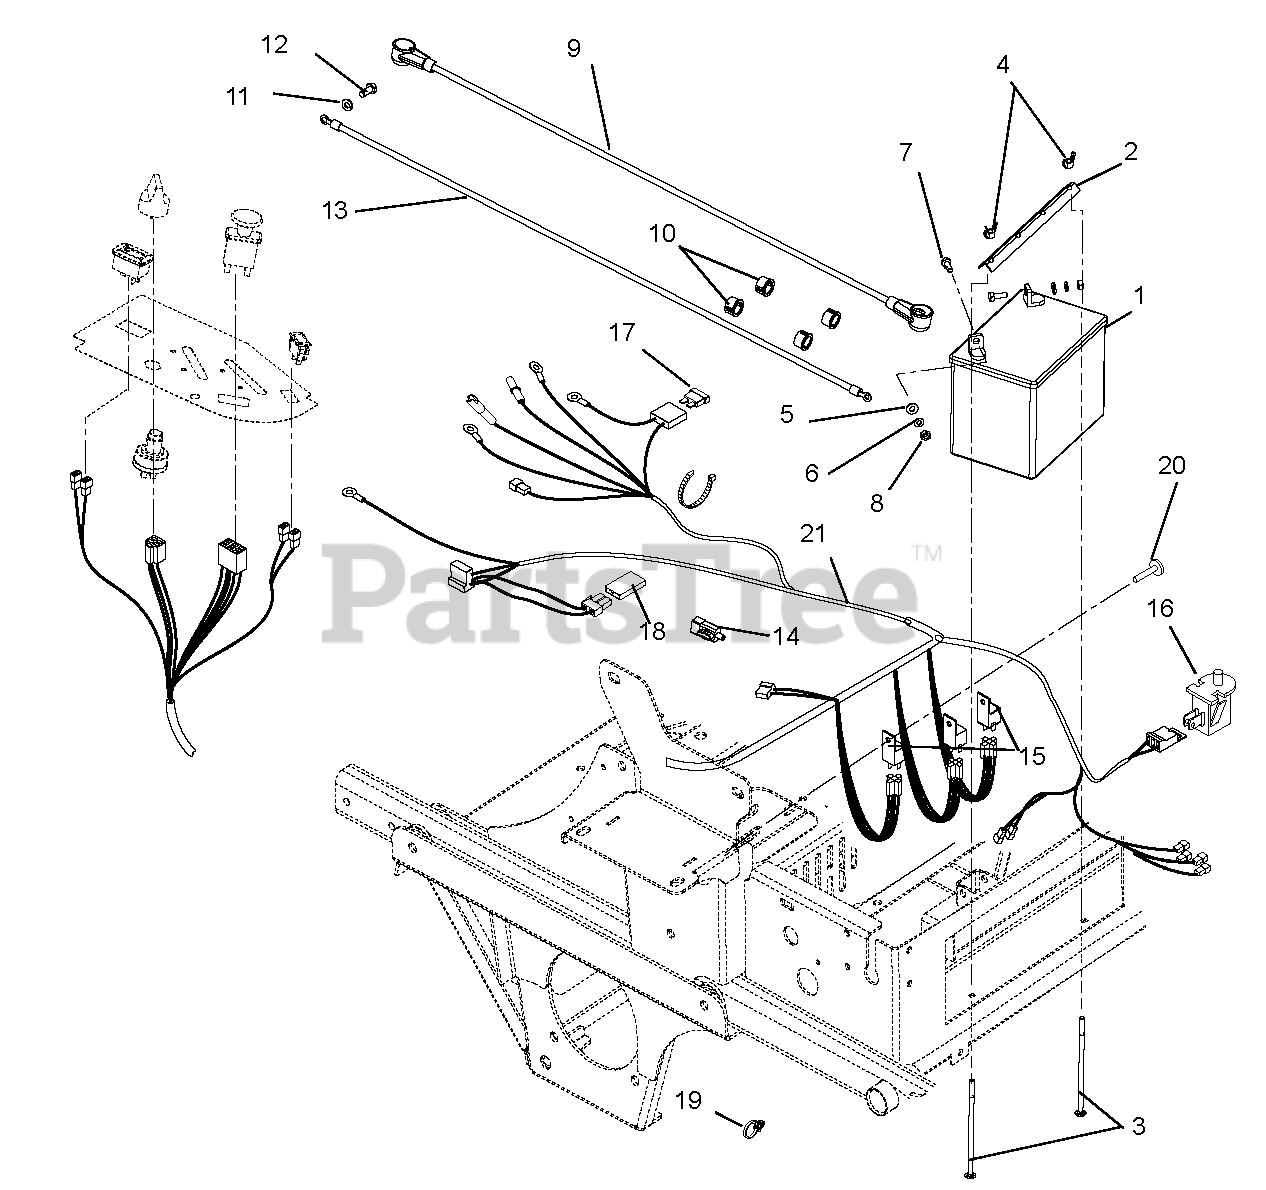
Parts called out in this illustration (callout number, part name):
1	Battery, SMF U1-9U1L/U1H
2	Hold Down
3	Bolt, Round Head Square Neck .25-20 x 7.50
4	Nut, Locking Wing .250-20
5	Washer, Flat-Steel .281 x .62 x .065
6	Washer, Locking .25 x .062 Regular
7	Bolt, Hex .25-20 x .75 Grade 5
8	Nut, Hex .25-20
9	Cable, POS Battery w/Boots 6 x 35
10	Bushing, Panel Snap .687 x .875 x .56
11	Washer, Locking .31 x .078 Regular
12	Bolt, Hex M8-1.25 x 20
13	Cable, Negative Battery 35.0"
14	Switch, Snap-In - N.O./N.O.
15	Relay (Included with Harness)
16	Switch, Snap Mounting
17	Fuse, 30 Amp (Included with Harness)
18	Diode, Connector Shell
19	Cable Tie with TREE (.25 HOLE)
20	Rivet, .25 Nylon Panel
21	Harness, Vertical A/C Wiring
